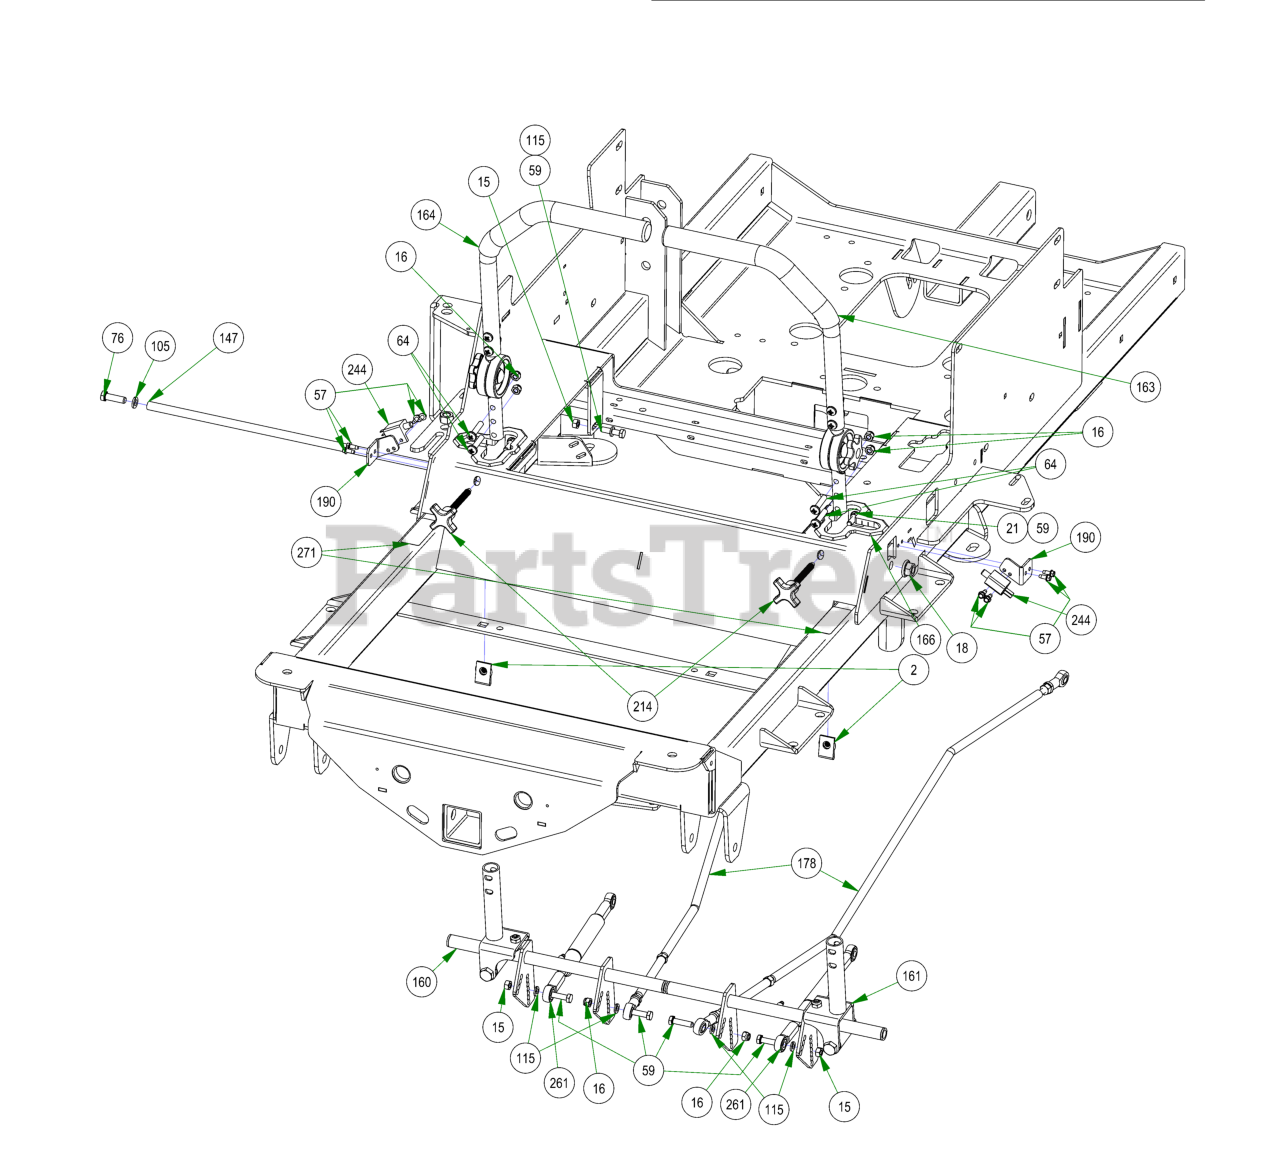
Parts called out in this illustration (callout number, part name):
2	Extruded Nut 3/8"-16 3/4" Hole Center With Patch
15	5/16-18 HEX NUT ZINC
16	5/16-18 NYL INS L/N ZC
18	1/2-13 NYLON INSERT FLANGE LOCKNUT ZINC
21	5/16-18 HEX SERRATED FLANGE NUT HARD/ZINC
57	12-24 X 1/2 HEX WASHER UNLSOT F TCS ZINC
59	5/16-18 X 1-1/4 HEX C/S (GR.5) ZC
64	5/16-18 x 1 3/8" Futton Head Torx Drive Bolt
76	3/8-16 X 1-1/4 HEX CAP SCREW (GR.5) ZINC
105	3/8 SPLIT LOCKWASHER ZINC
115	5/16 SPLIT LOCKWASHER ZINC
147	2019 Steering Actuator Rod
160	2019 R Series RH Arm Rod Assembly
161	2019 R Series LH Arm Rod Assembly
163	2019 Left Hand ADJ. Steering Arm Kit
164	2019 Right Hand ADJ. Steering Arm Kit
166	Snap-in Drive Arm Bushing
178	2019 Renegade Push Rod Assembly
190	2019 Arm Switch Bracket
214	Speed Limiting Knob 3/8-16X 3"
235	2022 Horizontal Diesel Frame
244	Safety Switch
261	2019 SROID Damper With Spherical Rod Ends
271	2018 LH/RH Steering Control Decal Roll
